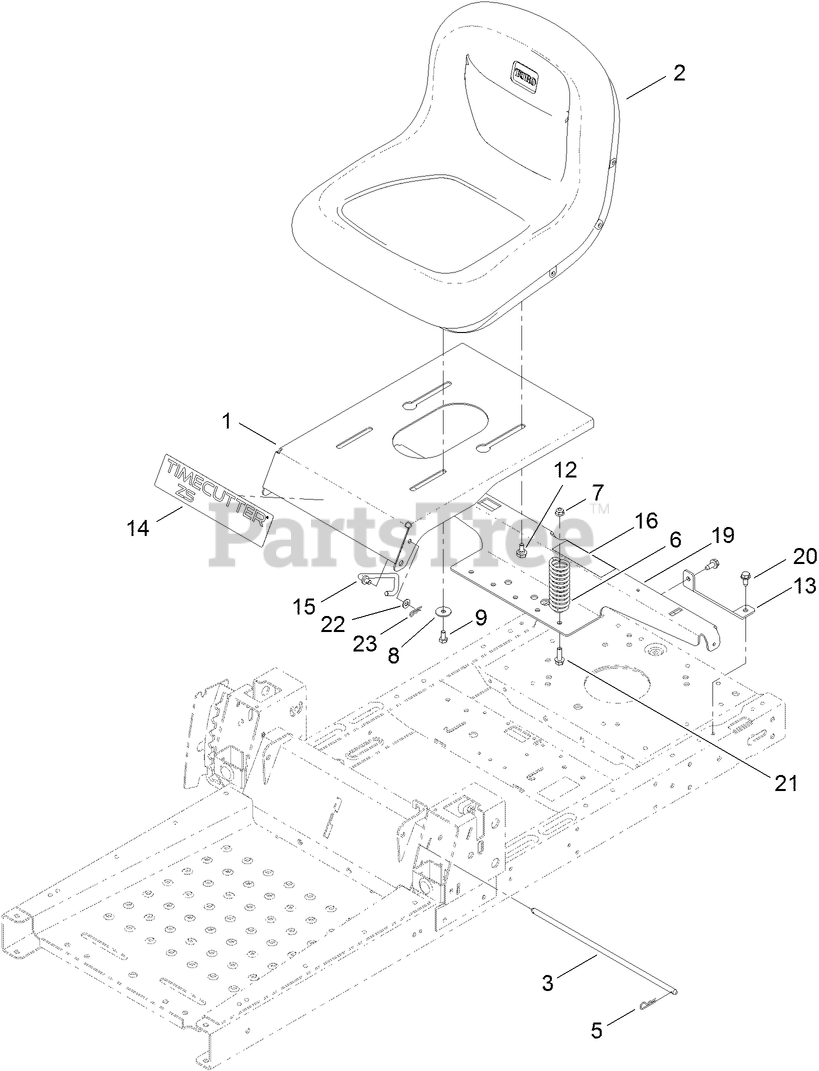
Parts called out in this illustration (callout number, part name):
2	SEAT-15 INCH
3	ROD-PIVOT, NARROW
5	PIN-COTTER
6	SPRING-COMPRESSION
7	NUT-HF, NI
8	WASHER-PIVOT
9	SCREW-HH
12	BOLT-SHOULDER,HFH
13	SUPPORT-TANK, REAR
14	DECAL-TIMECUTTER
15	STOP-SEAT
16	DECAL-SERVICE, CE
19	SUPPORT-POD
20	SCREW-HWHTF
21	SCREW-HHF
22	WASHER-PLAIN
